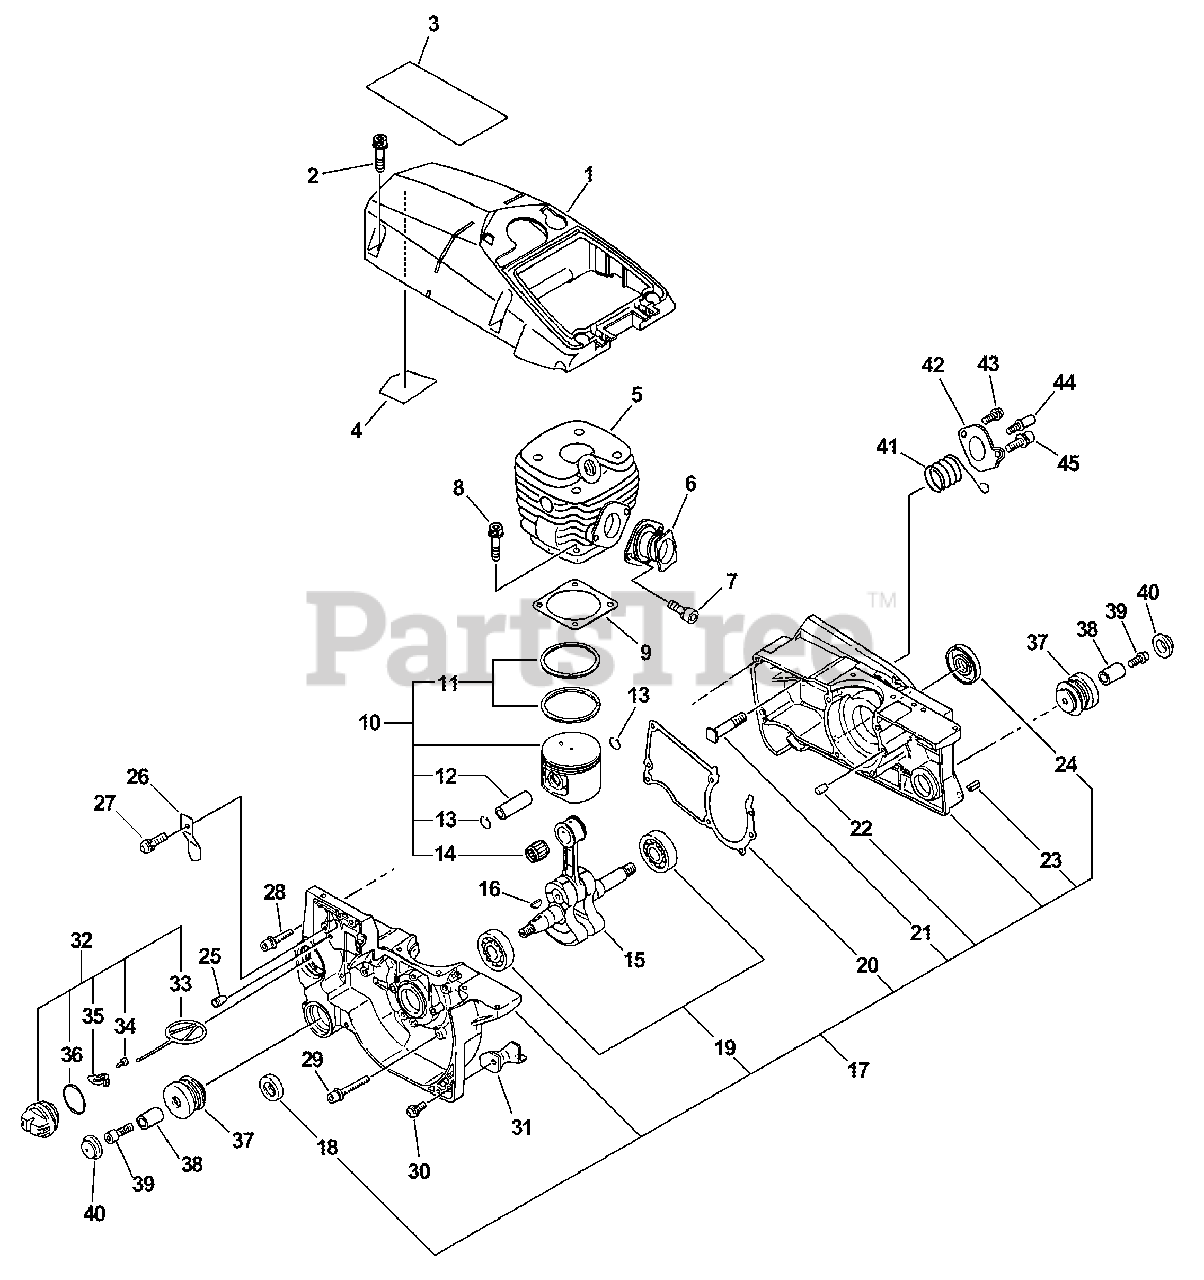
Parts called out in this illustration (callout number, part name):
1	COVER, ENGINE
2	BOLT 5×20
3	LABEL - KICK BACK
4	SHIELD, HEAT
5	CYLINDER
6	BELLOWS, INTAKE
7	BOLT 5×14
8	BOLT 5×25
9	GASKET, CYLINDER
10	PISTON KIT
11	RING, PISTON
12	PIN, PISTON 12
13	RING, SNAP
14	BEARING, NEEDLE
15	CRANKSHAFT ASSY
16	KEY, WOODRUFF
17	CRANKCASE KIT
18	SEAL, OIL
19	BEARING, BALL 6202
20	GASKET, CRANKCASE
21	STUD, GUIDE BAR 8
22	PIN, LOCATING 5×10
23	PIN, SPRING 5×10
24	SEAL, OIL
25	VENT ASSY
26	PLATE, EYE
27	SCREW 4×8
28	BOLT 5×20
29	BOLT M5×35
30	SCREW 5×14
32	CAP ASSY, OIL
33	CONNECTOR, CAP L= 60 MM
34	SCREW, TAPPING 3×8
35	RETAINER, CONNECTOR
37	CUSHION
38	COLLAR 5
39	BOLT 5×25
40	CAP, CUSHION
41	SPRING, COMPRESSION
42	PLATE, EYE
43	BOLT 4×8
45	BOLT 5×14
